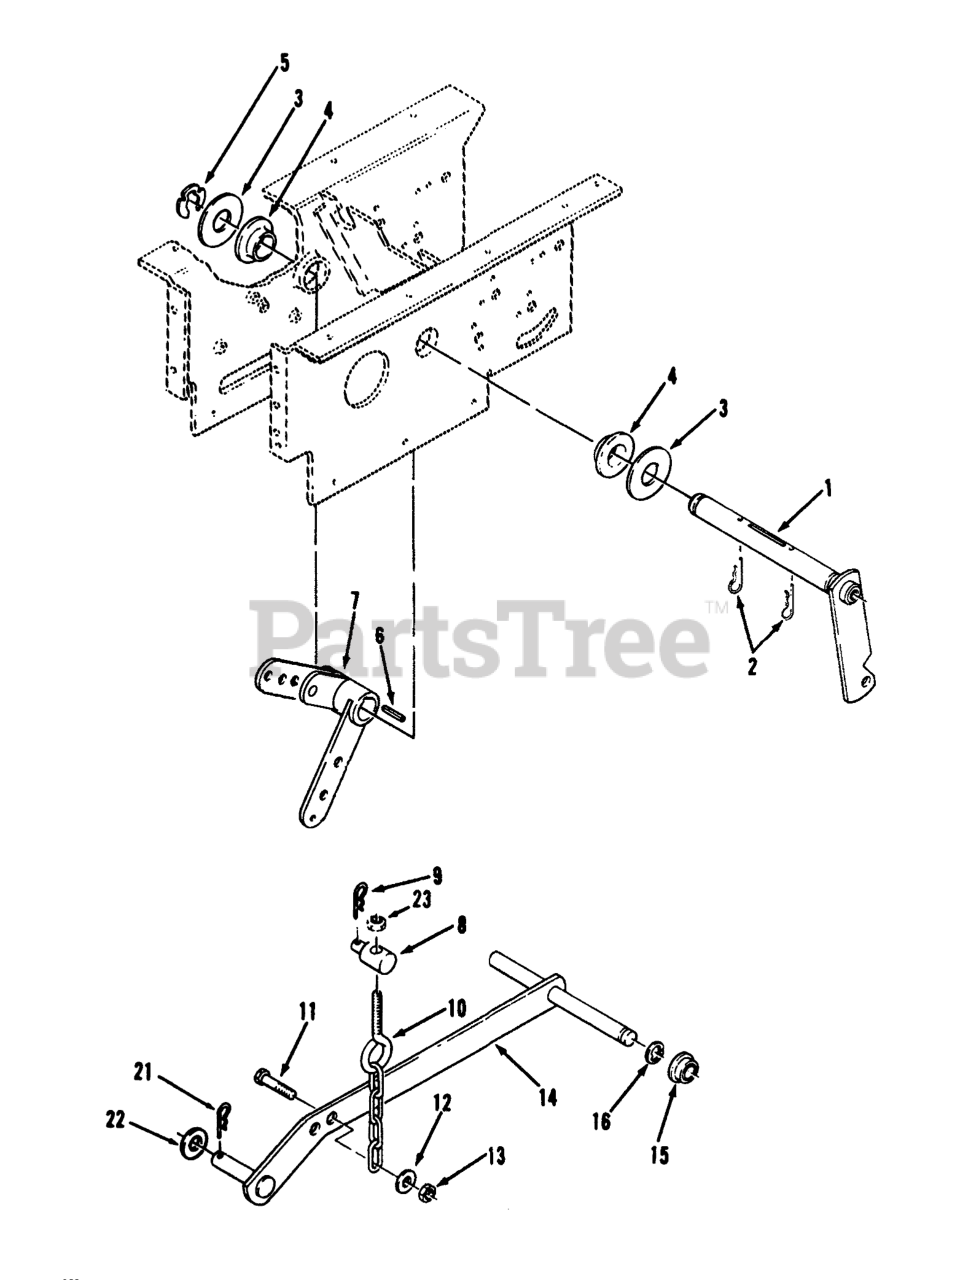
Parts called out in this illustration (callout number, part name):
1	WLDMT-LIFT ARM
2	Pin-Cotter
3	WASHER-FLAT
4	BEARING-FLANGE
5	RING-RETAINING
6	KEY-SQUARE
7	LIFT LEVER ASM
8	TRUNNION-LIFT
9	PIN-HAIR
10	CHAIN-LIFT
11	SCREW-HH
12	WASHER-PLAIN
13	NUT-LOCK, NI
14	Bar-Lift
15	BUSHING
16	RING-RETAINING, EXTERNAL
21	PIN-HAIR
22	WASHER-FLAT
23	NUT-LOCK, NI
